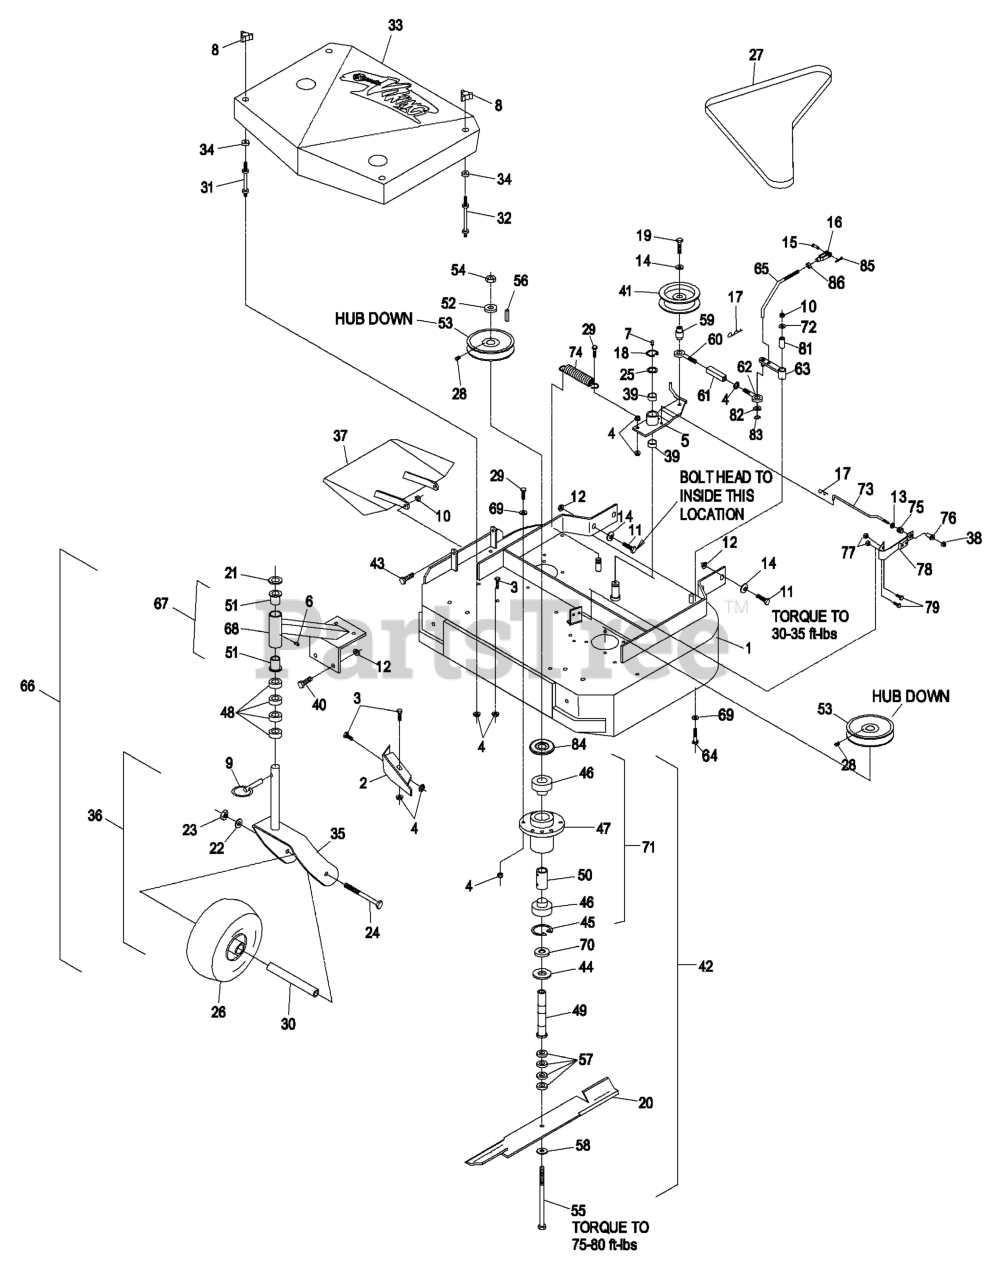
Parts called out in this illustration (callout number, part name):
1	ASM,DECK 36 RIGID
2	BAFFLE-DOGLEG
3	SCREW-HH
6	FITTING-GREASE
7	FITTING-GREASE
8	KNOB-3 PRONG
10	NUT-LOCK, NI
11	SCREW-HH
12	NUT-HHF, WHIZ
13	RING-PUSH ON
14	WASHER-BELLEVILLE
15	PIN-CLEVIS
16	YOKE-ADJUSTABLE
17	PIN-COTTER
18	RING-RETAINING, EXT
19	SCREW-HH
21	WASHER-FLAT
22	WASHER-LOCK
23	NUT-HH
24	SCREW-HH
25	WASHER-SPINDLE
27	BELT,BLADE VIKING HYD 36
28	SCREW-SET
29	SCREW-HH
30	SPACER FRONT CASTER
31	STUD-SHIELD, BELT (SHORT)
32	STUD-SHIELD, BELT (LONG)
36	ASM,CASTER/WHEEL
37	WLD,CHUTE 36 RIGID
38	NUT-LOCK, NI
39	SLEEVE-BEARING
40	SCREW-HH
43	SCREW-HH
44	GUARD-BEARING, BOTTOM
45	RING-SNAP
46	BEARING
48	SPACER-CASTER
49	TUBE-SPINDLE, SHORT
50	SPACER-BEARING
51	BEARING-FLANGED
52	WASHER-RETAINER, SHEAVE
54	NUT-HEX
55	SCREW-CAP, HH
58	WASHER-SPRING
59	BUSHING-ENGAGEMENT
60	EYEBOLT-THREAD, LH
61	BODY-TURNBUCKLE
62	EYEBOLT-THREAD, RH
63	ARM-ASSIST, 32/36
64	SCREW-HH
65	ARM-LINKAGE, ASSIST
67	ASM,CSTR SUPPORT W/WEIGHT
69	WASHER-SPRING
70	SPACER-PULLEY/BEARING
72	WASHER-FLAT
73	ROD-BRAKE
74	SPRING-EXTENSION
75	SPRING-COMPRESSION
76	SPACER-FLANGED
77	NUT-LOCK, NI
78	PAD AND SPRING ASM
79	SCREW-HH
81	TUBE-PIVOT
82	WASHER-PLAIN
83	RING-RETAINING, EXT
84	GUARD-BEARING, TOP
85	PIN-COTTER
86	NUT-HEX
87	KIT, SP CASTER WHEEL REPL
